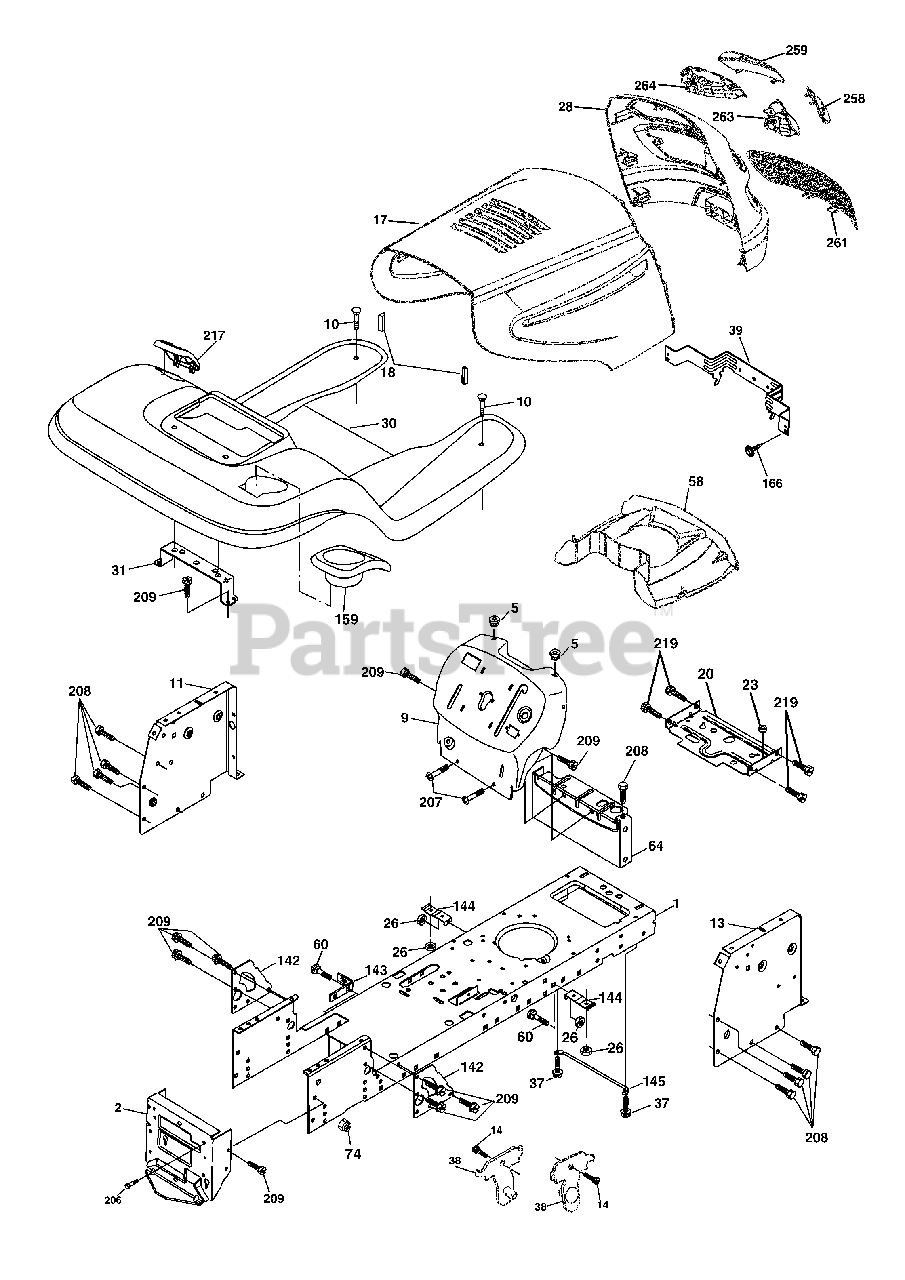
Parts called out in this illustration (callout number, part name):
1	Chassis
2	Drawbar
5	Bumper Hood/Dash
9	Dash P/L
10	Bolt Carriage 3/8-16 x 1
11	Panel Dash Lh
13	Panel Dash Rh
14	Screw Thdrol 3/8-16 x 1/2
17	Hood
18	Bumper Hood
20	Plate Battery
23	Bushing
26	Nut Lock Hex W/Ins 3/8-16 unc
28	Grille/Lens Asm
30	Fender Footrest STLT Pnt
31	Bracket Fender
37	Screw Thdrol 6/16-18 x 1/2 TYT
38	Bracket Asm Pivot Mower Rear
39	Bracket Pivot
60	Bolt RDHD Sqnk 3/8-16 unc x 3/4
64	Dash Lower STLT
74	Nut Crownlock 3/8-16 unc
90	Nut Self Thd Wsh - HD 1/4 Zinc
142	Plate Reinforcement STLT
143	Bracket Swaybar Chassis
144	Bracket Footrest Step-thru
145	Rod Pivot Chassis/Hood
159	Cupholder
166	Screw Hwhd Hi-Lo #13-16 x 3/4
206	Bolt Shoulder 5/16-18
207	Screw Thdrol 5/16-18 x 1/2
208	Screw Thdrol 3/8-16 x 1/2
209	Screw Hexwsh Thdr 3/8-16 x 3/4
217	Console Fuel Window
219	Screw 5/16-18 x 3/4
258	Lens Grille Pro RH
259	Lens Grille Pro LH
263	Bezel Grille LH
264	Bezel Grille RH
